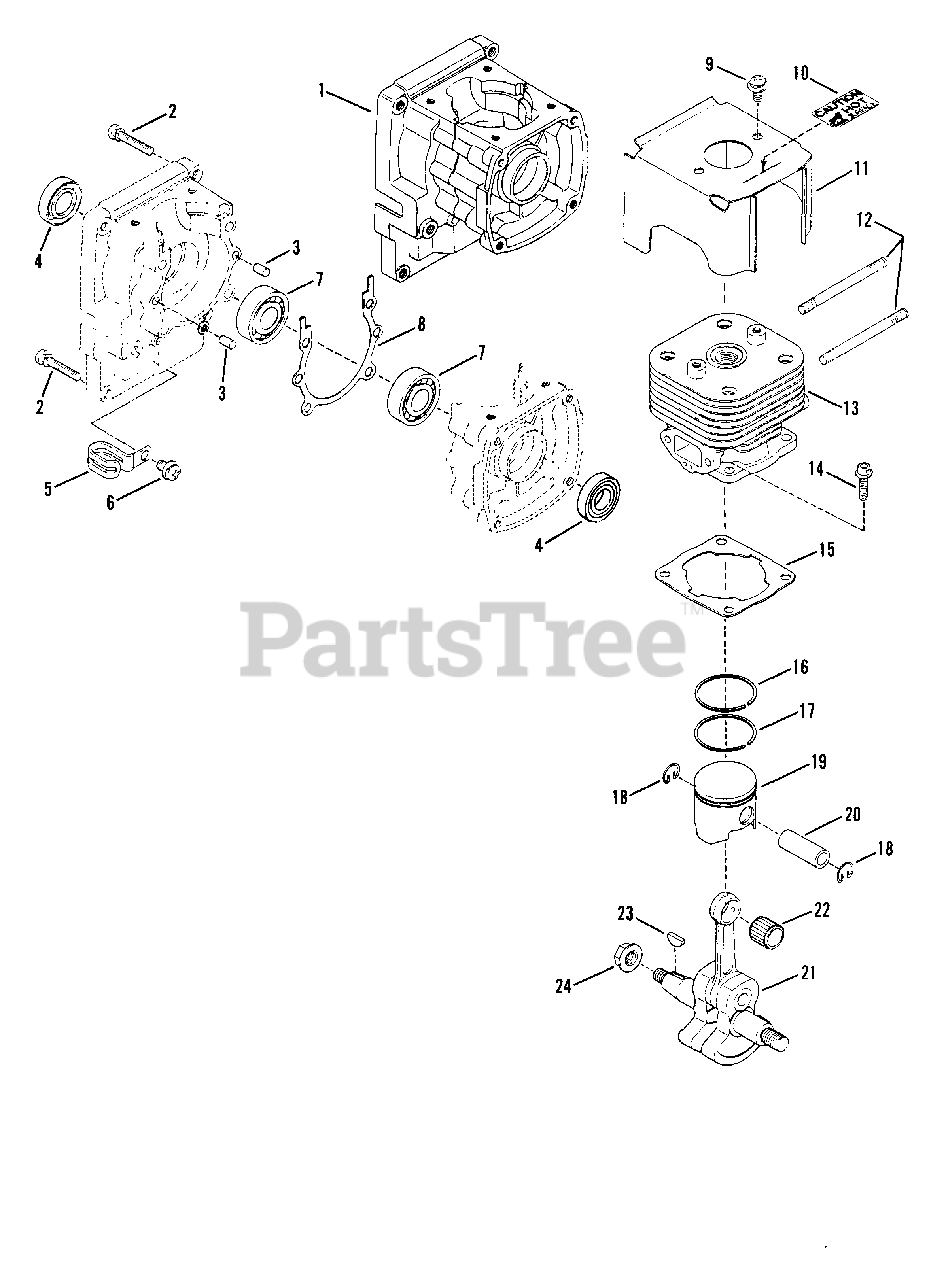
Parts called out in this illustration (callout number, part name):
1	CRANKCASE ASSM'Y.
3	PIN, Dowell
4	SEAL, Oil
7	BEARING, Ball
8	GASKET, Crankcase
10	DECAL, Caution
11	COVER, Cylinder
13	CYLINDER
14	BOLT, Socket Flange
15	GASKET, Cylinder
16	RING, Piston (Upper)
17	RING, Piston (Lower)
18	SNAP-RING, Piston Pin
19	PISTON
20	PIN, Piston
21	CRANKSHAFT
22	BEARING, Needle
23	KEY, Woodruff
24	NUT, Crankshaft
